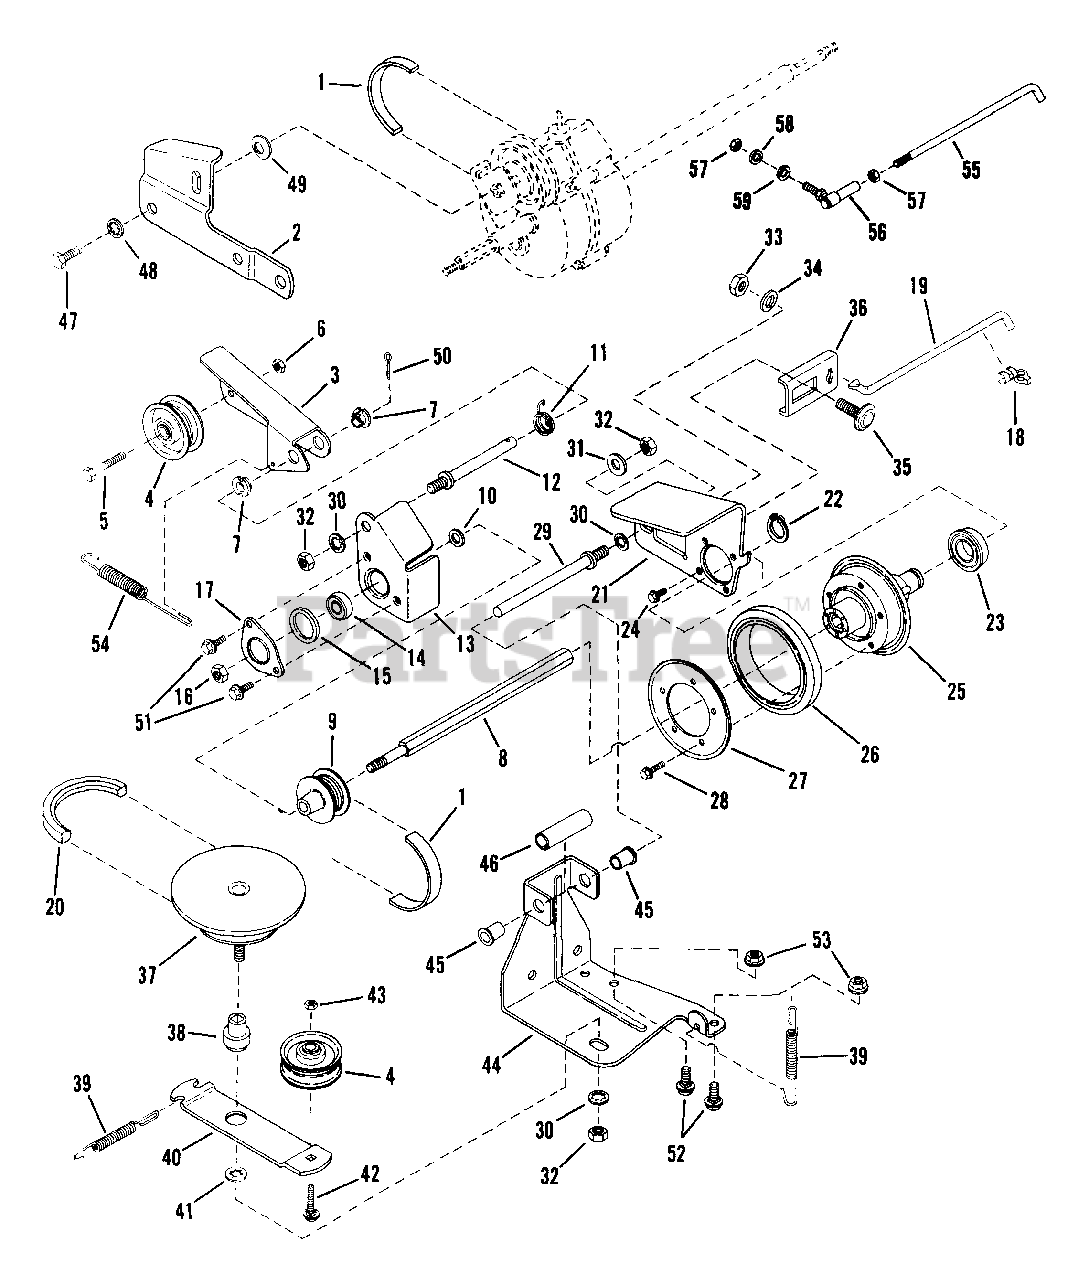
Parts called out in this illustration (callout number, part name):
1	BELT, Poly-Vee
2	LINK, Differential
3	ARM, Clutch Idler
4	PULLEY, Idler
5	CAPSCREW, 1/4-28 x 1-3/8" Hex Head
6	NUT, 1/4-28 Hex Lock
7	BUSHING, 3/8 I.D. Nylon
8	SHAFT, Hex
9	PULLEY
10	WASHER
11	SPRING, Torsion
12	STUD
13	HOLDER, Bearing (Inner Half)
14	BEARING, Ball
15	O-RING
16	NUT, 3/8 Hex Center Lock
17	HOLDER, Bearing (Outer Half)
18	CLIP, 1/4 Right Arc (Transfer Rod)
19	ROD, Transfer
20	BELT, Engine Drive
21	PLATE, Thrust
22	RING, Retaining
23	BEARING, Ball
24	SCREW, #10-32 x 1/4" Self-Tapping Machine
25	ASSEMBLY, Hub
26	RING, Driven (Rubber Disc)
27	PLATE, Ring Retaining
28	SCREW, #10-24 x 1/2" Hex Washer Self-Tap (Torx)
29	GUIDE, Thrust Plate
30	WASHER, 3/8 Internal Tooth Lock
31	WASHER, 3/8" Flat
32	NUT, 3/8-24 Hex
33	NUT, 5/16-18 Hex
34	WASHER, 5/16 Split Lock
35	BOLT, 5/16-18 x 3/4 Carriage
36	CONNECTOR, Transfer Rod
37	ASSEMBLY, Drive-Disc
38	BUSHING
39	SPRING (Wheel Drive & Idler)
40	ARM, Idler
41	RETAINER, 3/8 Bolt
42	BOLT, 1/4-20 x 1-114" Carriage
43	NUT, 1/4-20 Hex Center Lock
44	BRACKET, Deck
45	BUSHING, Flange
46	SPACER
47	SCREW, 5/16-18 x 1/2" Hex Head Cap
48	WASHER, 5/16 Internal Tooth Lock
49	WASHER, Spring
50	COTTER-PIN, 3/32 x 1/2"
51	SCREW, 1/4-20 x 1/2" Self-Tapping
52	BOLT, 5/16-18 x 5/8" Short Neck Carriage
53	NUT, 5/16-18 Hex Flange Lock
54	SPRING, Clutch
55	LINK, Transfer ('89 Models & Later)
56	JOINT, Ball ('89 Models & Later)
57	NUT, 1/4-28 Hex ('84 Models & Later)
58	WASHER, 1/4 Flat ('89 Models & Later)
59	WASHER, 1/4 Internal Tooth Lock ('89 Models & Later)
